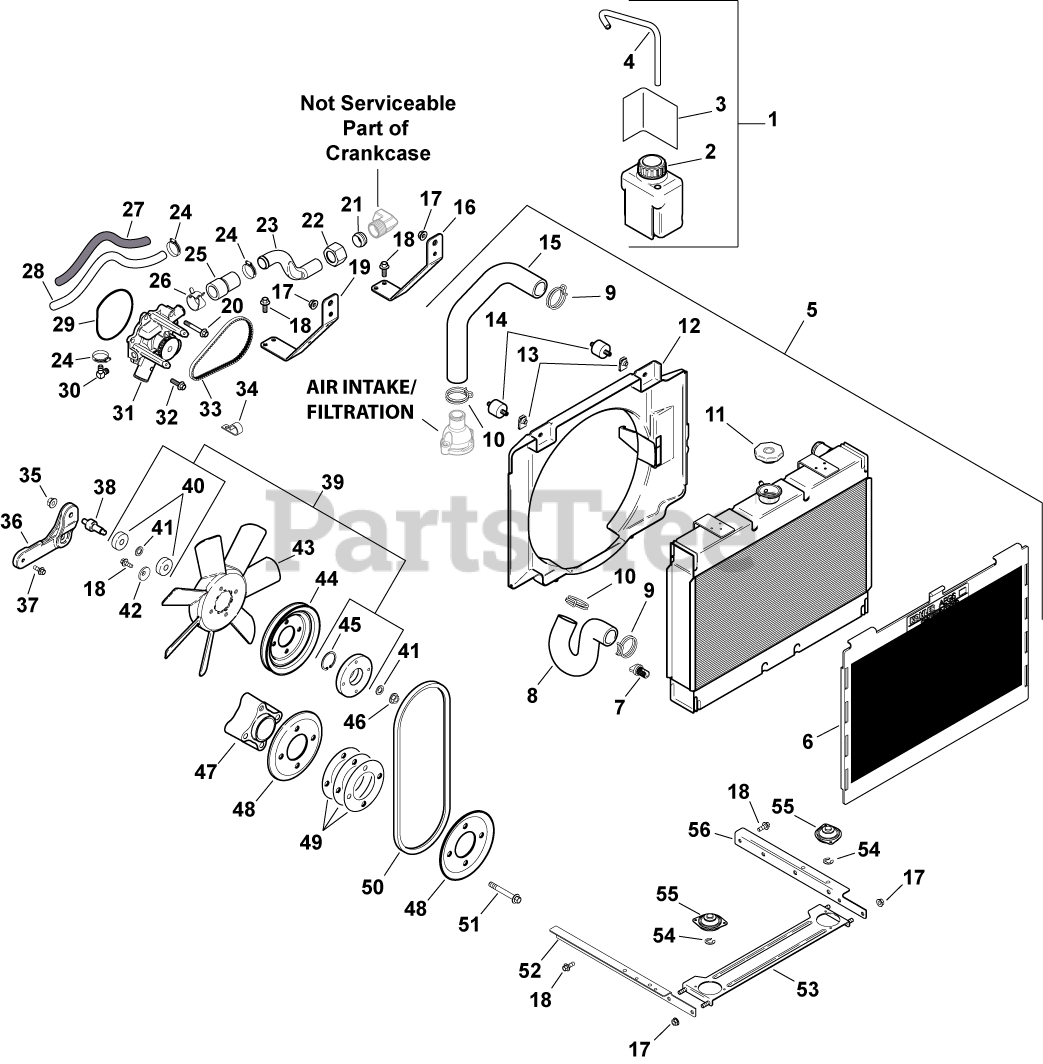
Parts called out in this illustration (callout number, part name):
1	KIT, OVERFLOW BOTTLE
2	CAP, OVERFLOW
3	DECAL, COOLANT LEVEL
4	HOSE, OVERFLOW
6	SCREEN, GRASS (FLAT)
7	PLUG, DRAIN
8	HOSE, RADIATOR TO WATER PUMP (LOWER)
9	CLAMP, CONSTANT TENSION BAND
10	CLAMP, THERMOSTAT HSG OUTLET
11	CAP, RADIATOR - (#6617309S)
12	SHROUD, FAN
13	U CLIP - DISCONTINUED
14	MOUNT, ISOLATION
15	HOSE, THERMOSTAT TO RADIATOR (UPPER)
16	BRACKET,UP RADTR #1 SIDE-USE 66 126 75-S
17	NUT, FLG M6X1.0
18	SCREW, FLG M6X1.0X16
19	BRACKET,UP RADTR #2 SIDE-USE 66 126 78-S
20	SCREW, FLG M6X1.0X40
23	TUBE, CROSSOVER - USE 66 755 16-S
24	CLAMP, HOSE-USE 25 237 32-S
25	HOSE, CROSSOVER - USE 66 755 16-S
27	SLEEVE, INSULATING 14"
28	HOSE, BY-PASS 13"
30	CONNECTOR
31	PUMP ASSEMBLY, WATER - USE 66 393 10-S
32	SCREW, FLG M6x1.0x20
33	BELT, WATER PUMP
34	CLIP, CABLE
35	NUT, FLG M8X1.25
36	BRACKET, FAN
37	SCREW, FLG 8X1.25X16
38	SHAFT, FAN - USE 66 144 11-S
39	KIT, BEARING CARRIER
40	BEARING, BALL
42	WASHER, SPRING 1/4"
43	FAN, AXIAL PULLER
44	PULLEY, FAN
45	RING, RETAINER-INTL O.D. 30MM
46	NUT, FLG M8X1.25
47	ADAPTER, CRANKSHAFT PULLEY
48	PULLEY, CRANKSHAFT
49	SHIM, CRANKSHAFT PULLEY
50	BELT, FAN
51	SCREW, FLG M8X1.25X60
52	BRCKT KIT, LWR RADIATOR #2
53	BRACKET, RADIATOR CROSS
54	RETAINER, E-CLIP
55	MOUNT, PLATEFORM
56	BRCKT KIT, LWR RADIATOR #1
